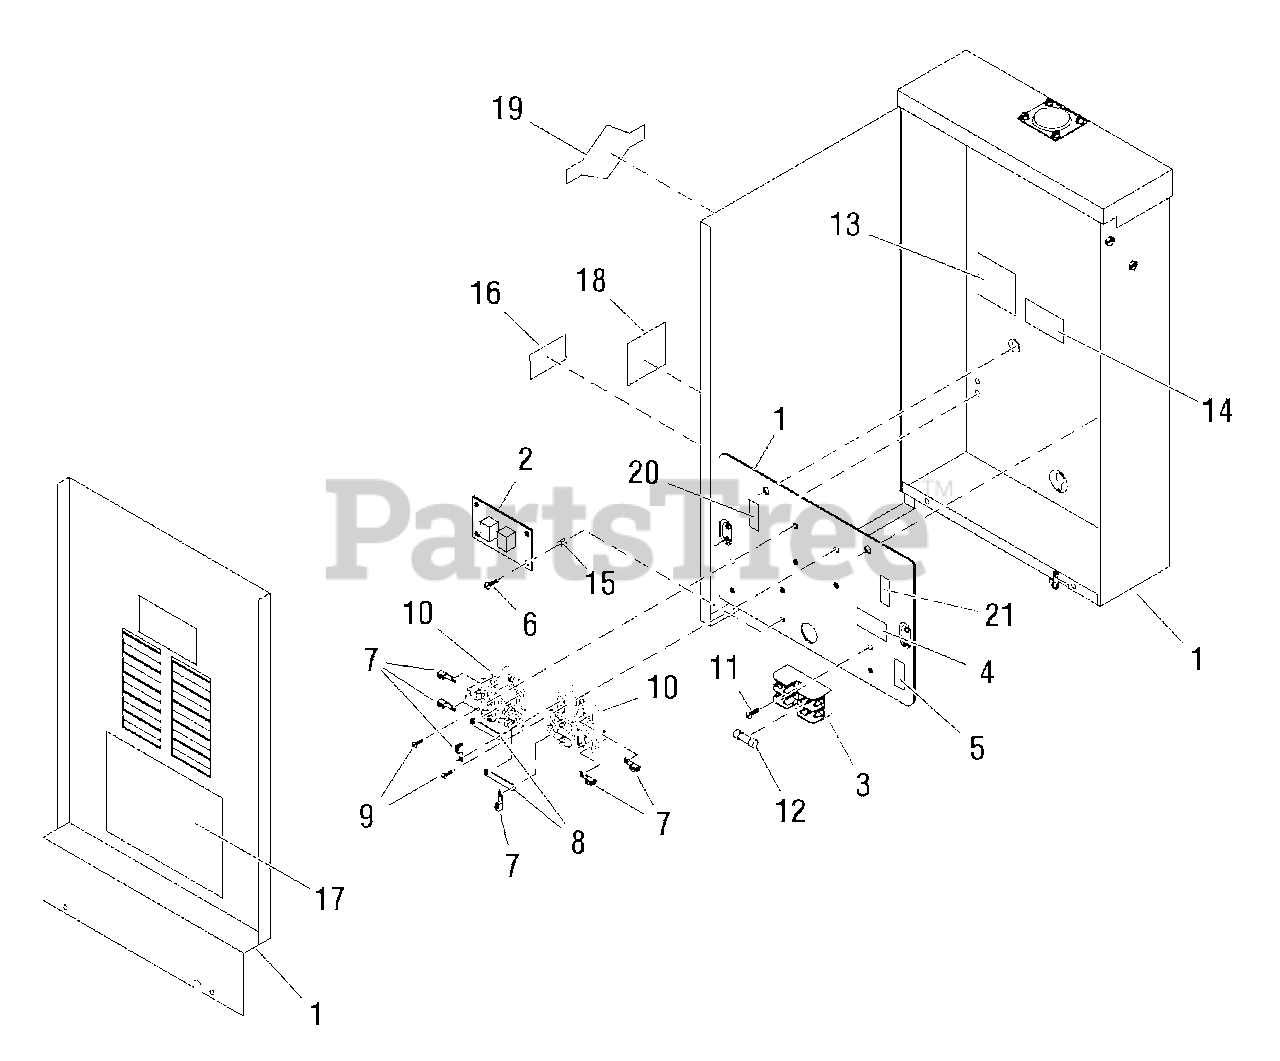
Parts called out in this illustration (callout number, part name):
1	LOADCENTER
5	DECAL
7	TERMINAL
